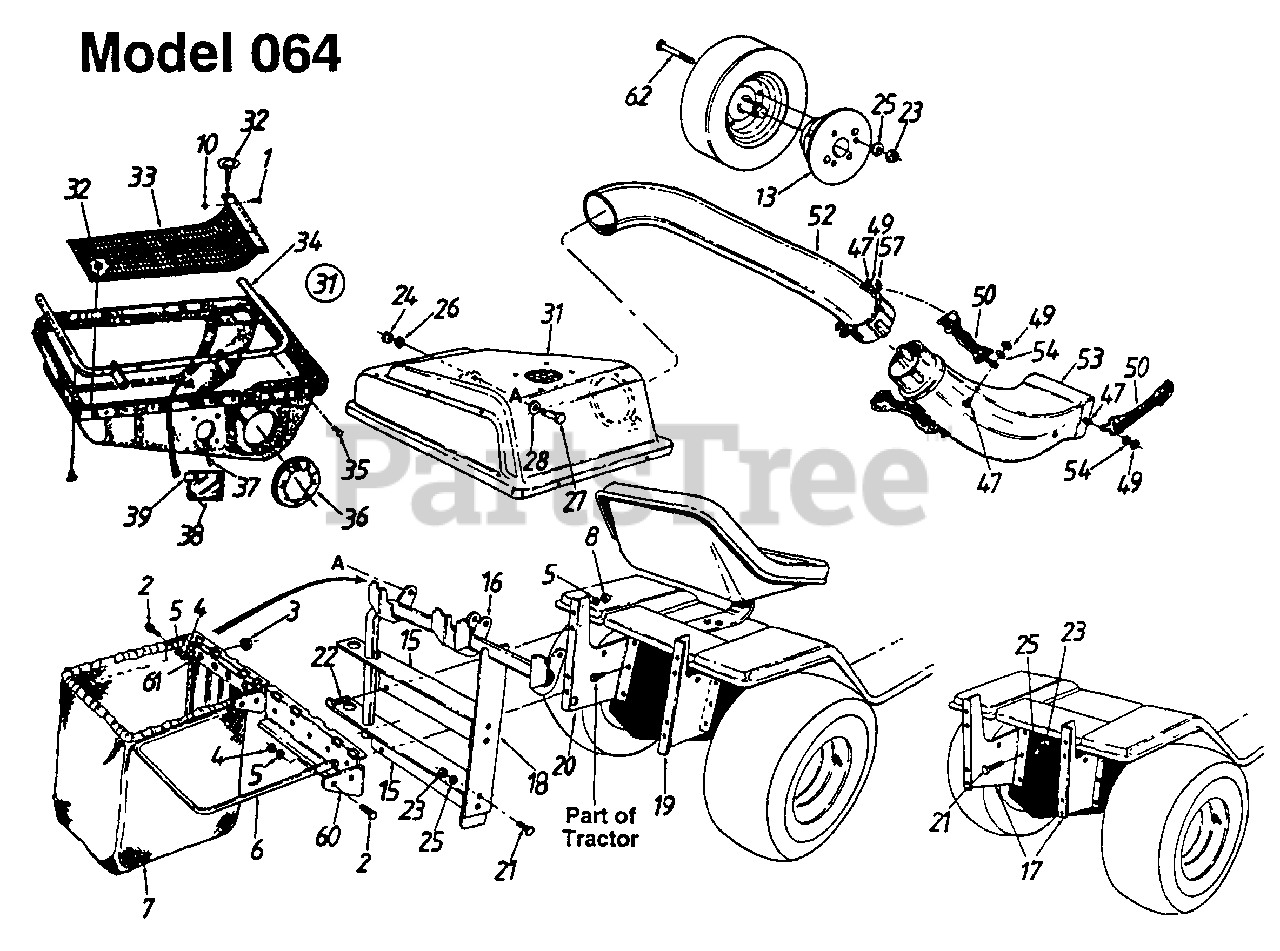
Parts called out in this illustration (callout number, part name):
1	Pop Rivet .188 Dia.
2	Hex Bolt 1/4-28 x .88" Lg.
3	Hex Sems Nut #10-24 Thd.
4	Hex Nut 1/4-28 Thd.
5	L-Wash. 1/4" I.D.
7	Grass Catcher Bag
8	Hex Nut 1/4-20 Thd.
10	Flat Wash. 1/4" I.D.
22	Hex Bolt 1/4-20 x .62" - Gr. 5
23	Hex Nut 5/16-18 Thd.
24	Hex Nut 3/8-16 Thd.
25	L-Wash. 5/16" I.D.
26	L-Wash. 3/8" I.D.
27	Shld. Bolt 3/8-16 x .50" Dia.
28	Bell-Wash. .505" I.D. x 1.0" O.D.
31	Grass Catcher Cover Ass'y.
32	Twist Fastener
35	Hex AB-Tap Scr. 1/4 x .62"
37	Truss B-Tap Scr. #10 x .5"
38	Plastic Plate
39	Speed Nut
47	Hex Bolt 1/4-20 x .625"
49	Hex Ins. L-Nut 1/4-20 Thd.
50	Retainer Strap Ass'y.
52	Catcher Tube
53	Discharge Chute
54	L-Wash. .27" I.D.
57	Retainer Hook Brkt.
61	Truss Mach. Scr. #10-24 x .5"
62	Hex Bolt 5/16-18 x .4" Lg.
